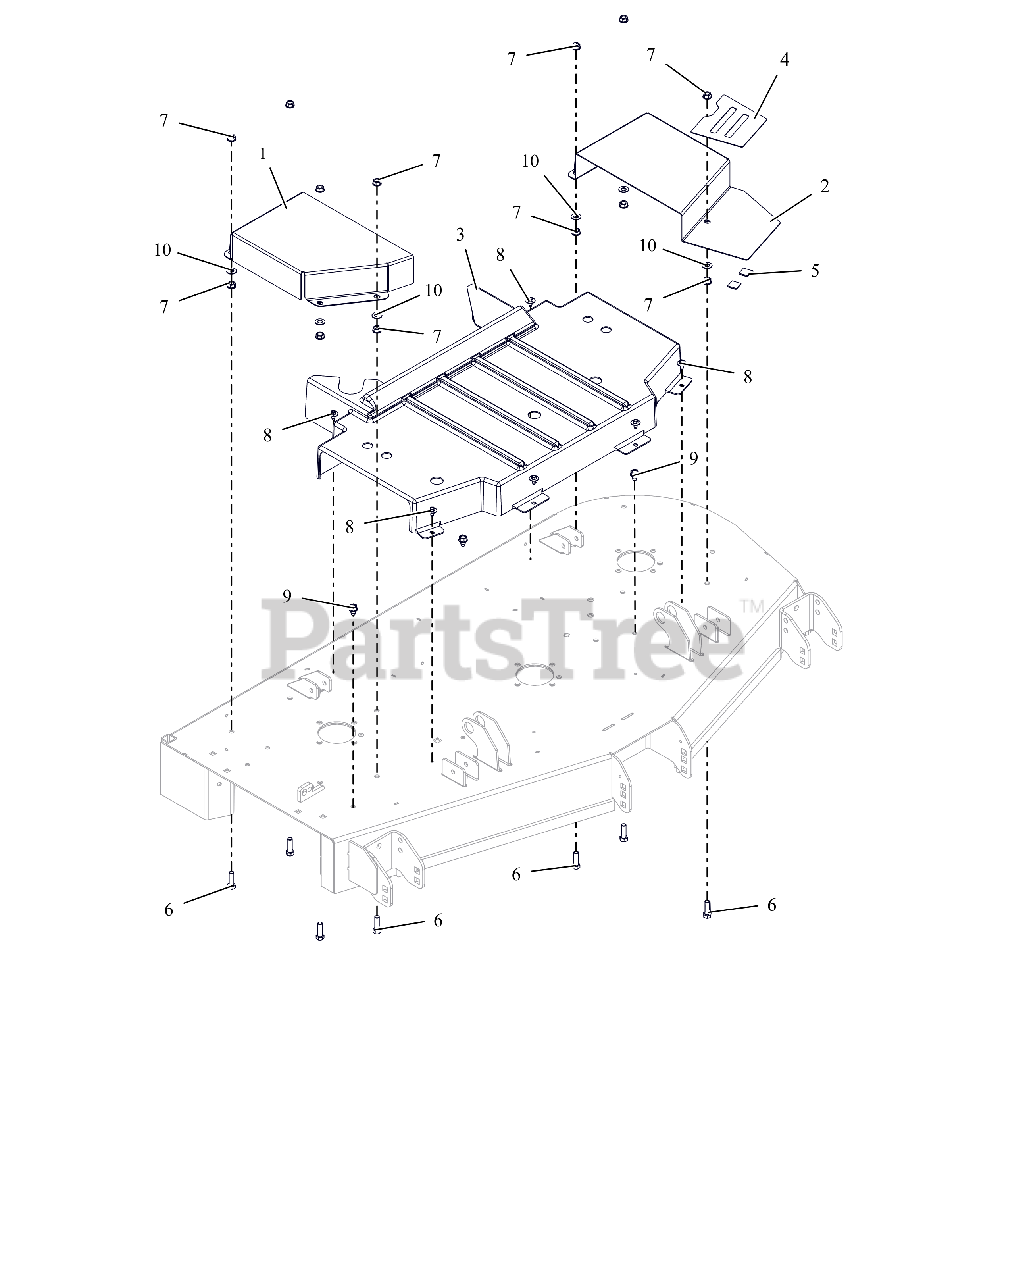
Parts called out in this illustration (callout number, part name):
1	GUARD,BELT 52" RIGHT CE
2	GUARD,BELT 52" LEFT CE
3	GUARD,CENTER,DECK SPINDLE CE
4	GRIP TAPE 52-60 BELT COVER
6	BLT, HEX .38-16X1.25 G5 ZCC
7	NUT, SPNLK-FLG .38-16 G5 ZCC
8	SCR, TAP .25-20X.50 LG HWH ZCC
9	SCR,TAP .375-16X.50 HWH TR ZCC
10	WSHR,FLT .406X.812X.065 ZCC
